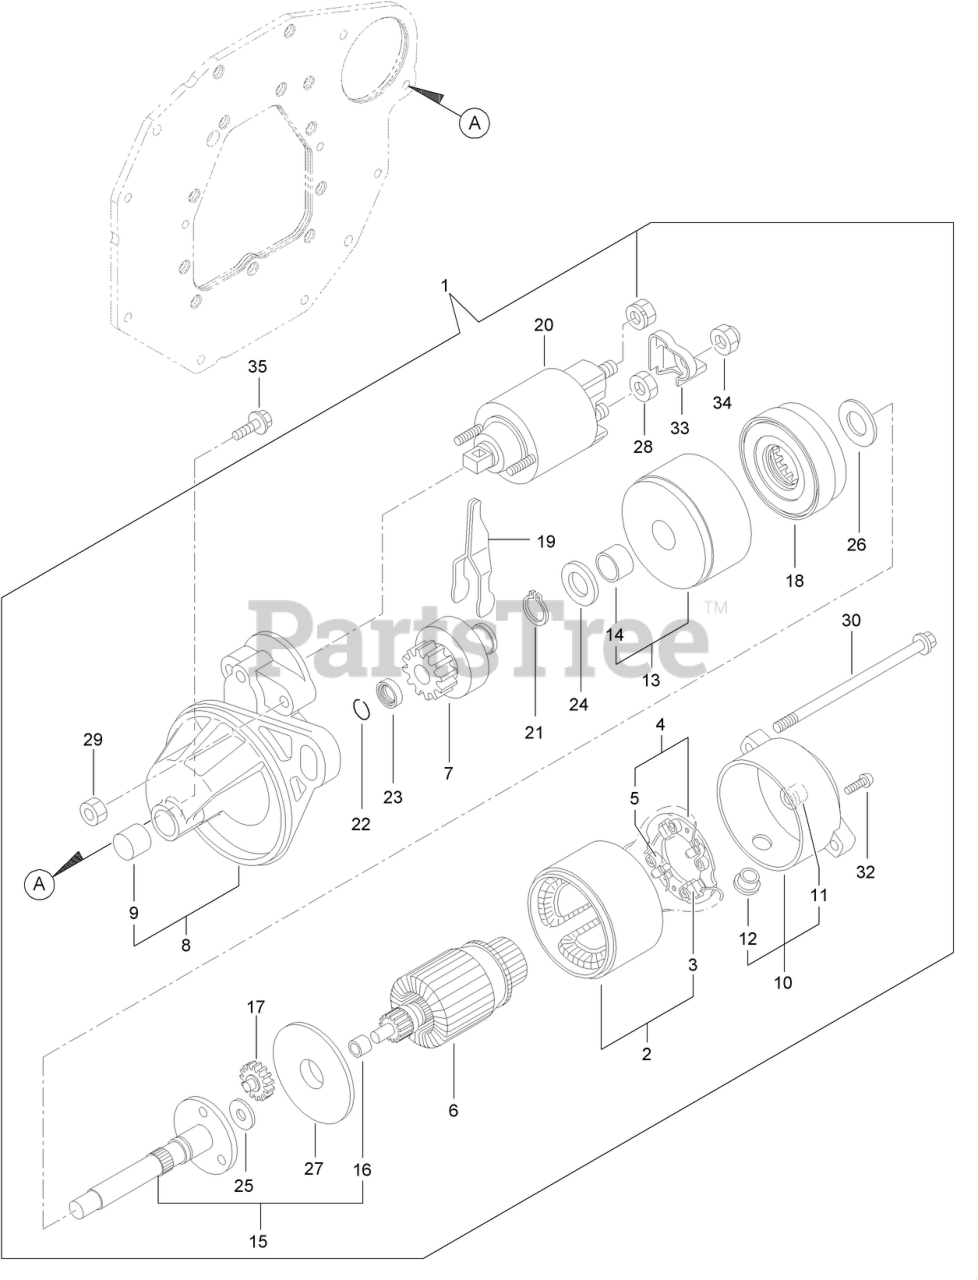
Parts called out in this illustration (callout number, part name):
1	STARTER ASM
2	YOKE ASM
3	STARTER KIT
4	HOLDER ASM
5	SPRING
6	ARMATURE ASM
7	CLUTCH ASM
8	HOUSING ASM
9	BEARING, NEEDLE 1
10	FRAME ASM
11	BEARING
13	BEARING ASM
14	BEARING
15	SHAFT ASSY 1
16	BEARING
20	SWITCH ASM
24	WASHER
25	WASHER
26	WASHER
30	BOLT-THROUGH
33	COVER-TERMINAL
